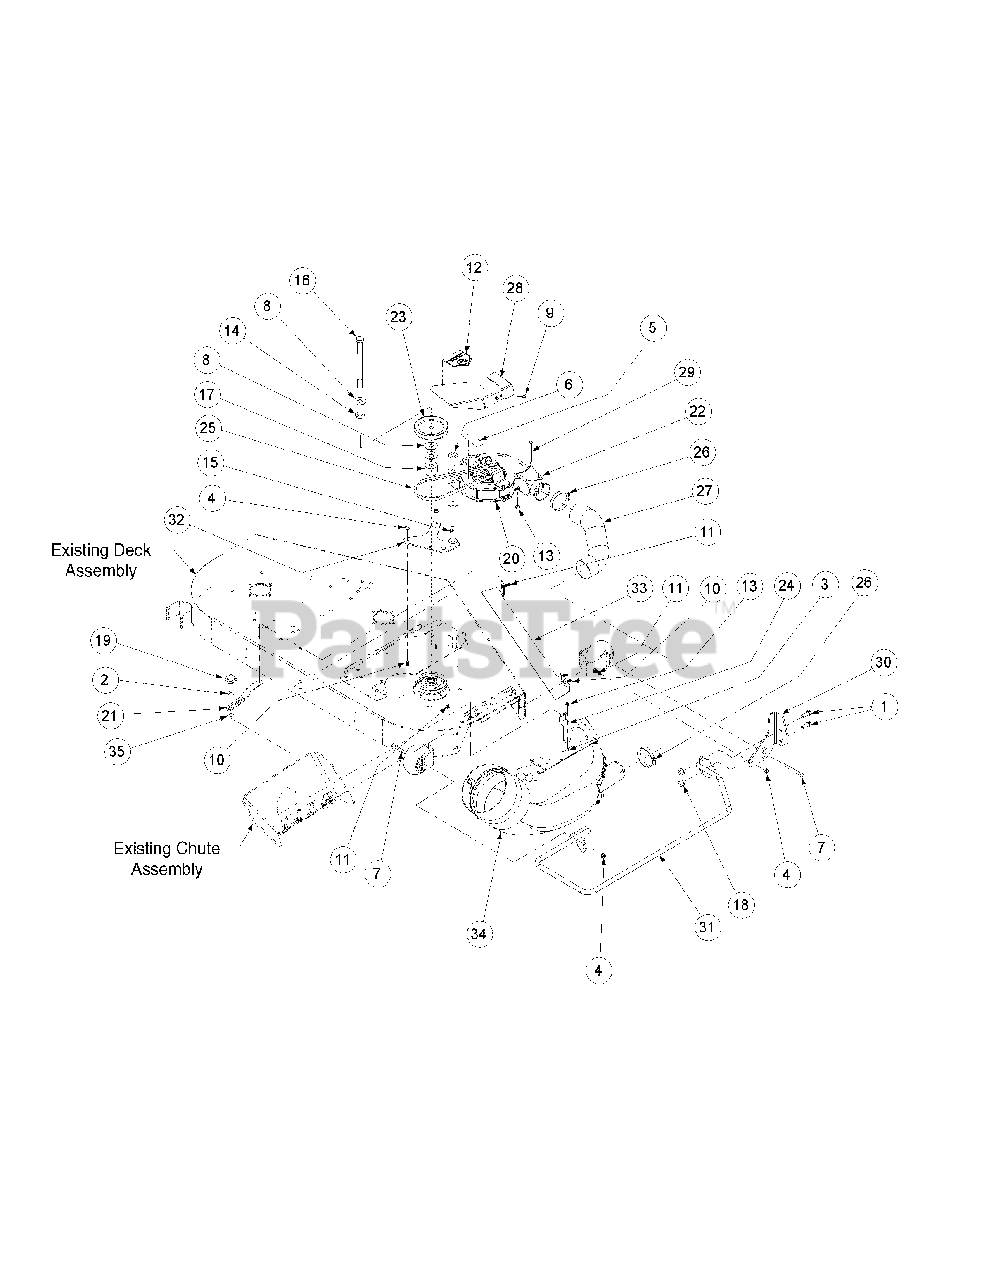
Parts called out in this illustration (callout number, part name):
1	HHCS, 1/2-13 x 1.25
2	Flat Washer, 3/8
3	Hex Cap Screw, 1/4-20, .75
4	Hex Nut Flange Lock, 3/8-16
5	Decal, Warning Shield Missing
6	Flat Washer, .76 x 1.49 x .06
7	HHCS, 3/8-16 x 4.50
8	Flat Washer, .781 ID x 2.00 OD x .105
9	Screw, TT, 1/4-20, 0.5, Hex Index Washer
10	Carriage Bolt, 3/8-16 x 1
11	Carriage Screw, 3/8-16 x 1.25
12	Decal, Danger Hands & Feet
13	Lock Nut, 1/4-20
14	Spacer, .812 ID x .268 Lg.
15	Cotter Pin, .148 x 3.00
16	Hex Cap Screw, 3/4-16, 9.00
17	Spacer, .76 OD x 2.00 OD x 1.39
18	Nut, 1/2-13, Flange Lock
19	Plastic Knob
20	Blower Assembly
21	Tension Assembly
22	Adaptor Tube
23	Pulley, V-Type 5.5 Dia.
24	Chute Stop Deflector Bracket
25	V-Belt
26	Hose Clamp, 3.00 Dia.
27	Hose Duct
28	Deck Blower Deflector Cover
29	HHCS, 1/4-20 x 3.50
30	MCS Guard Plate
31	MCS Guard Weldment
32	Pivot Weldment
33	Baffle Bracket
34	Chute Elbow Assembly
35	Push Retainer
